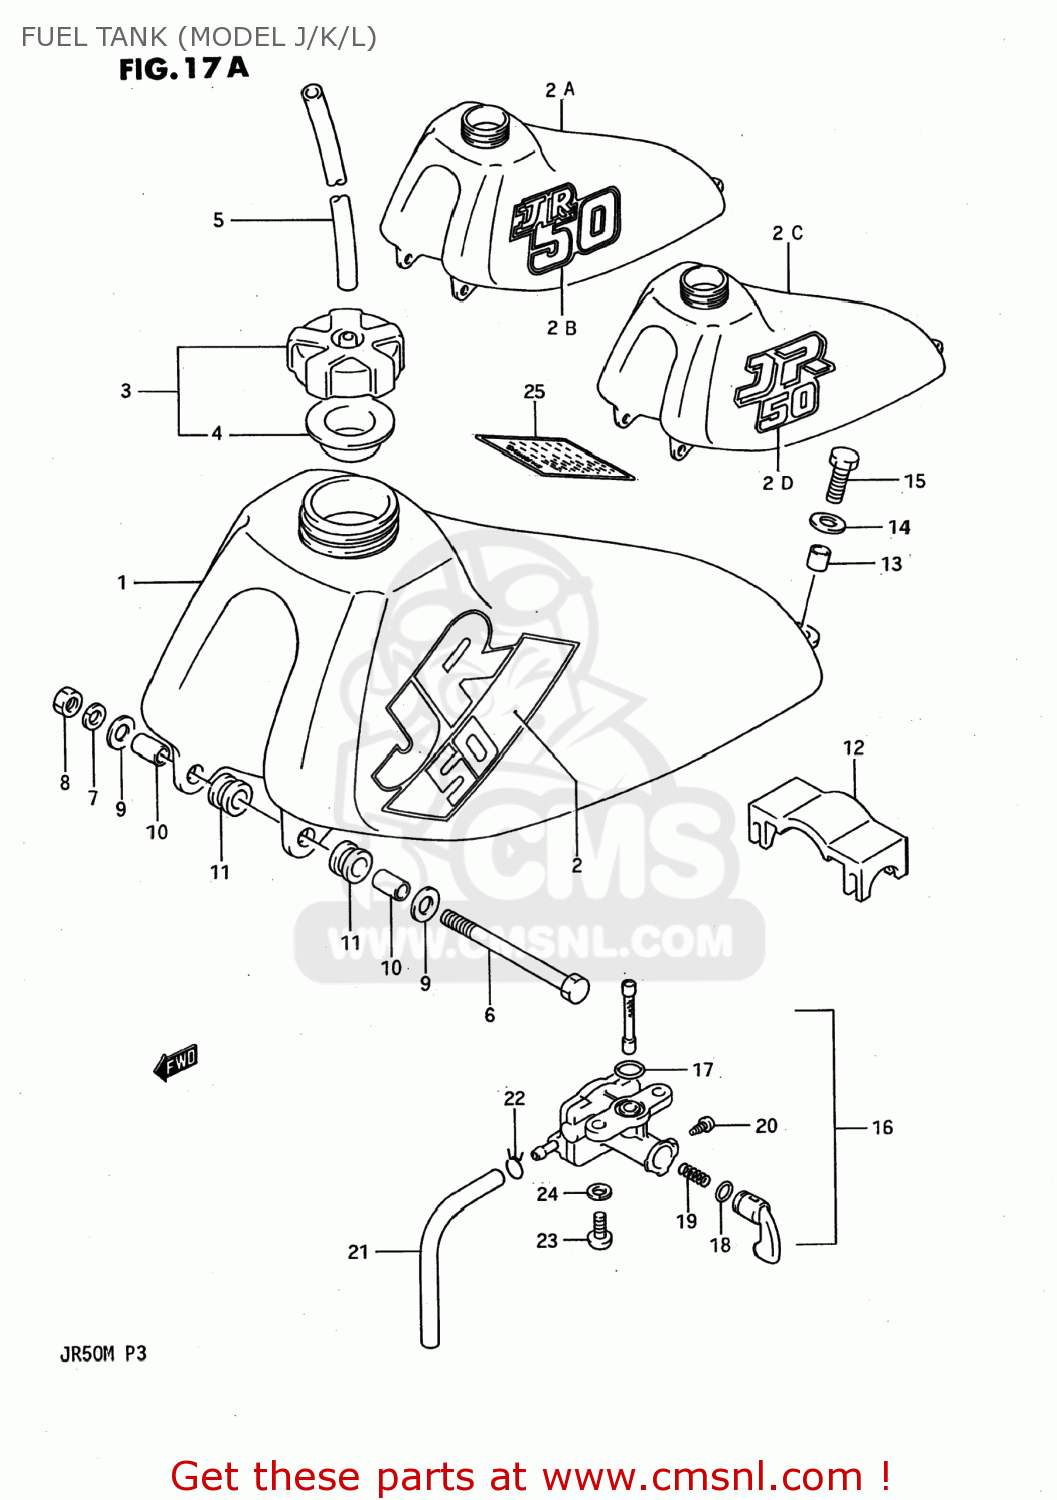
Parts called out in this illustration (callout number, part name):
1	TANK ASSEMBLY,FUEL
2	TAPE SET,FUEL TANK
2A	TANK ASSEMBLY,FUEL
2B	TAPE,FUEL TANK
2C	TANK,FUEL
2D	EMBLEM,FUEL TANK
3	CAP,FUEL TANK FILLER
4	GASKET,FUEL TANK CAP (NAS)
5	HOSE
6	BOLT
7	WASHER,LOCK
8	NUT 6MM
9	WASHER(6.5X18X1)
10	SPACER (6.8X10X11.5)
11	CUSHION
12	CUSHION,FUEL TANK UPR
13	SPACER
14	WASHER(6.5X18X1)
15	BOLT
16	COCK ASSY,FUEL
17	O RING
18	O RING,LEVER
19	SPRING,FUEL COCK VALUE
20	SCREW
21	HOSE
22	CLIP
23	SCREW
24	WASHER,LOCK
25	LABEL (WARNING)
